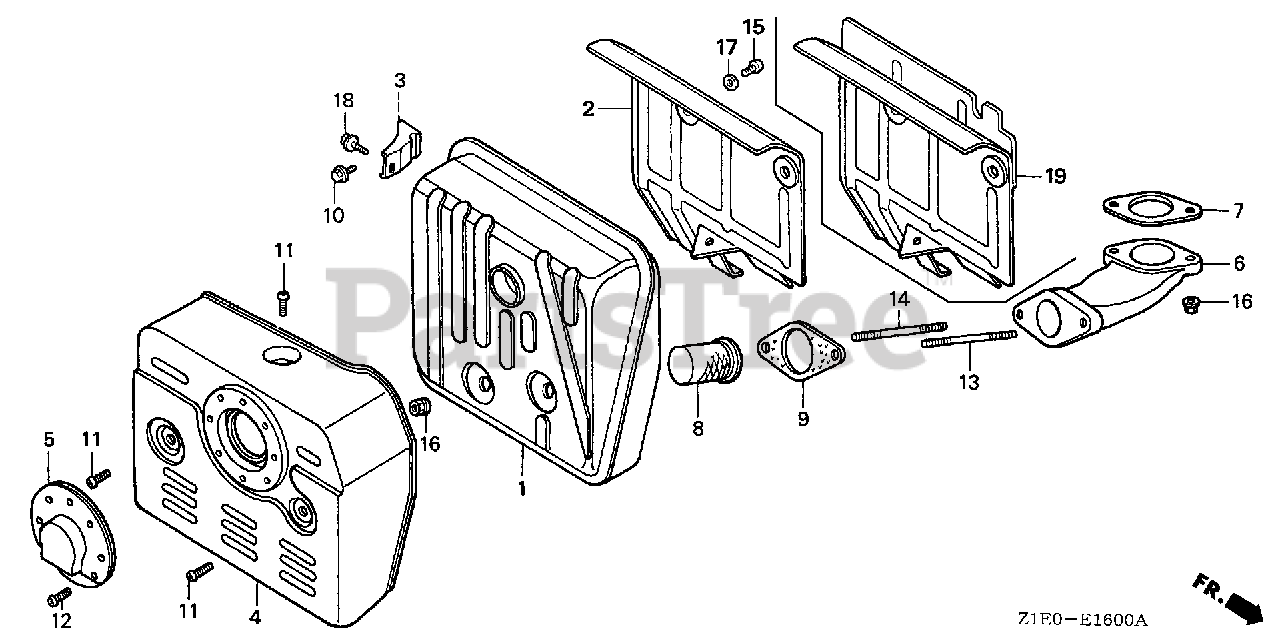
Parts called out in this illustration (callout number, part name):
6	PIPE, EX.
7	GASKET, EX. PIPE
9	GASKET, EX. PIPE
16	NUT, FLANGE (8MM)
